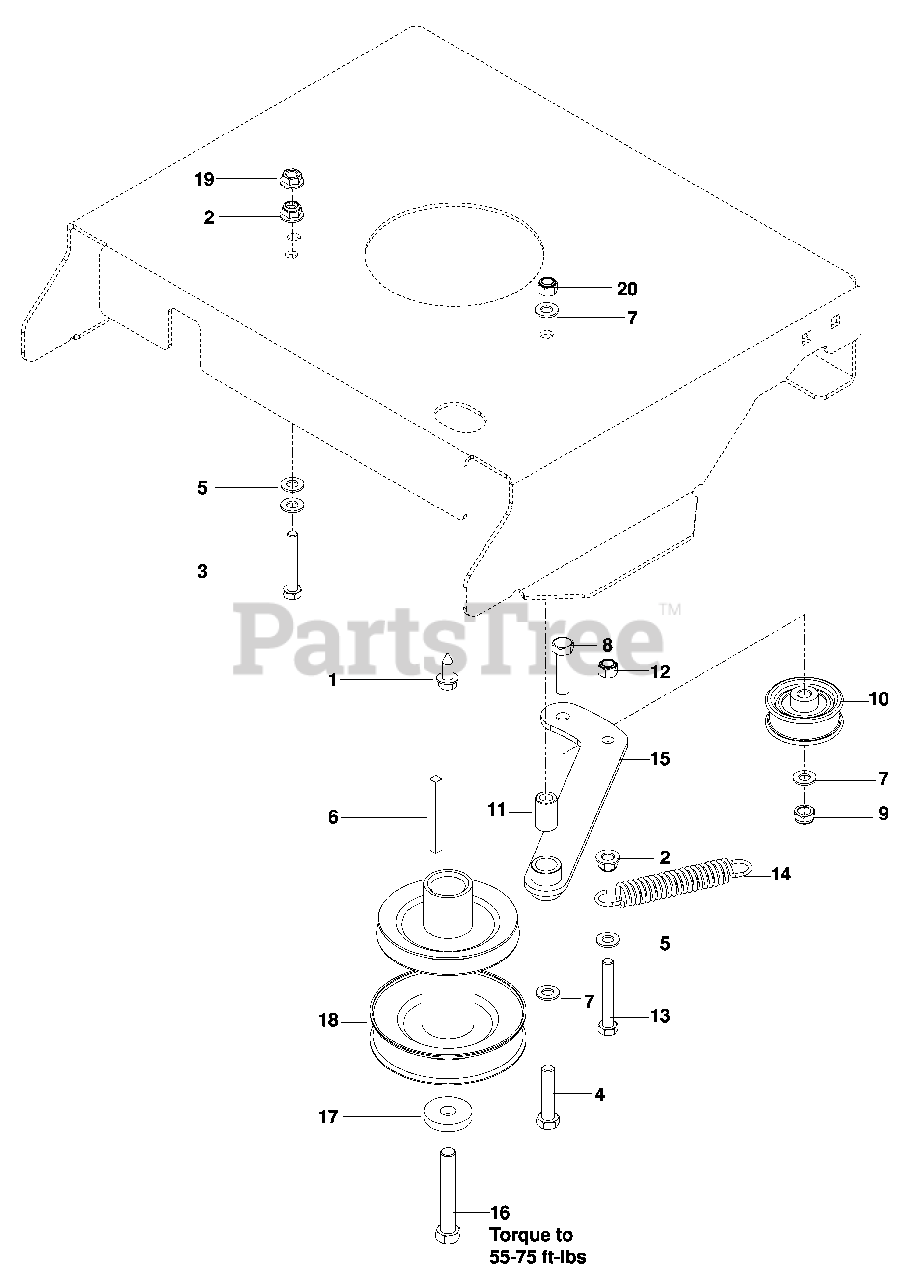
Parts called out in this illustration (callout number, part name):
1	HHFS 3/8-16 x 1 THD FRM
2	NUT 5/16-18 FLANGE NYLOC
3	BOLT, HEX HD 5/16-18 x 2
4	BOLT, HEX HD 3/8-16 x 2
5	WASHER 5/16 SAE FLAT
6	KEY ¼ SQ x 2½ LG
7	WASHER 3/8 FLAT STD
8	BOLT, HEX HD 3/8-16 x 1½
9	NUT 3/8-16 HEX JAM NYLOC
10	PULLEY, IDLER
11	BUSHING, METAL
12	NUT 5/16-18 HEX NYLOC
13	BOLT, HEX HD 5/16-18 x 2¼
14	SPRING 3½
16	BOLT, HEX HD 7/16-20 x 2¾
18	PULLEY, ENGINE
19	NUT 5/16-18 HEX WHIZLK
20	NUT 3/8-16 HEX NYLOC
